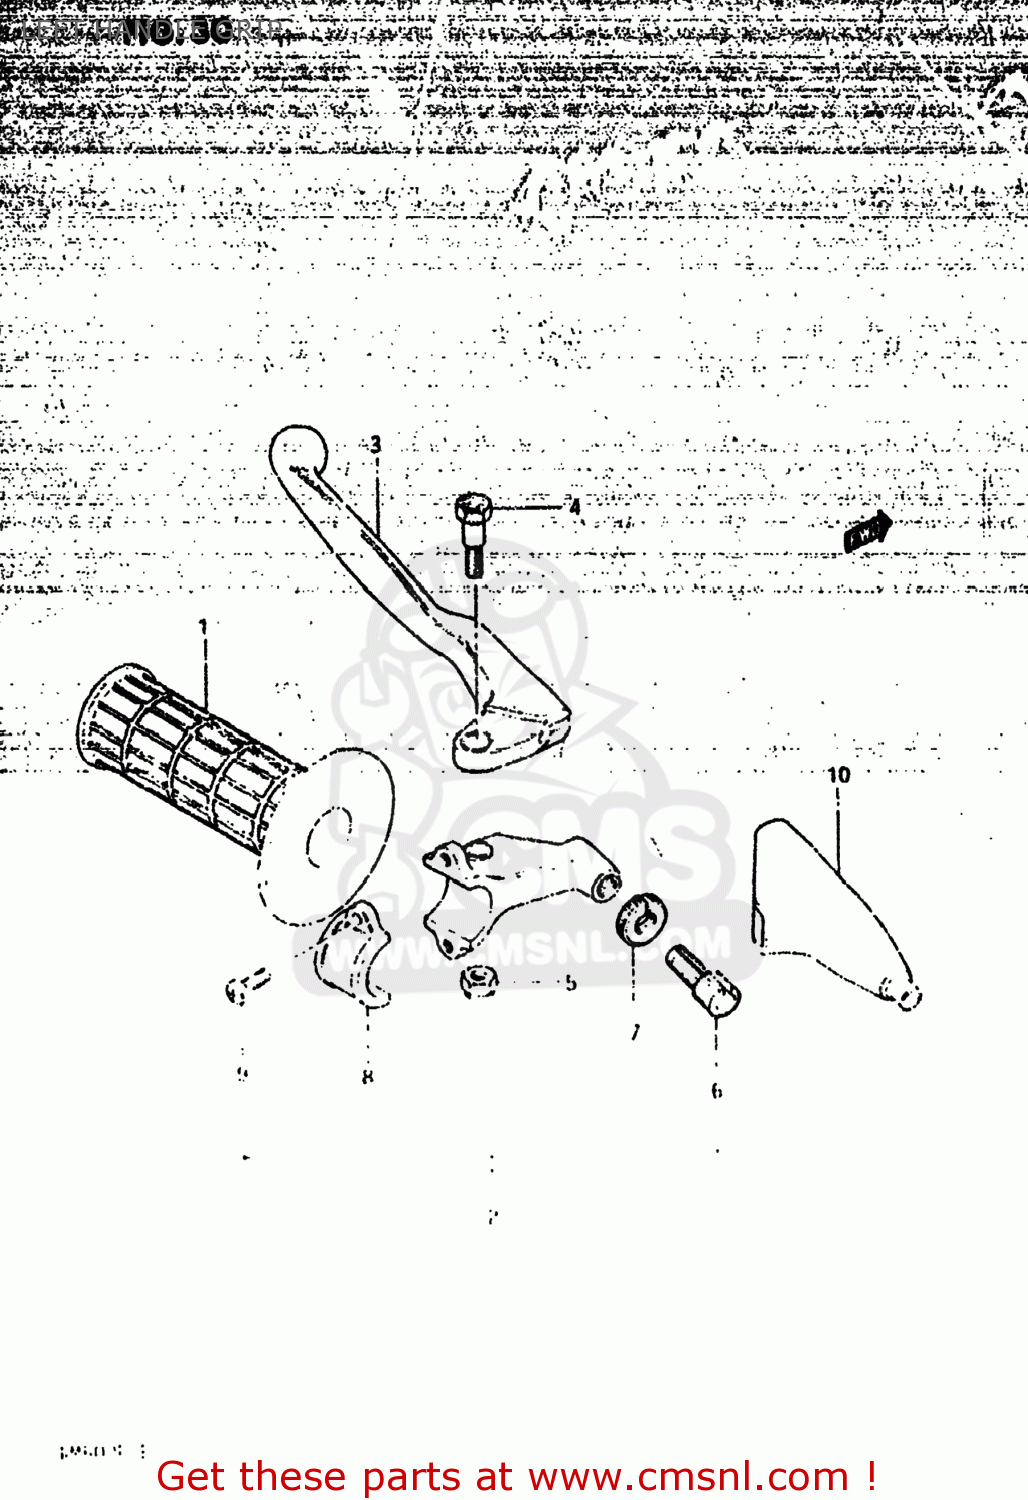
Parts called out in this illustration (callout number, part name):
1	GRIP,LEFT
2	LEVER ASSY,CLUTCH
3	LEVER,CLUTCH
4	BOLT,LEVER
5	NUT 6MM
6	ADJUSTER,CABLE
7	NUT,CABLE ADJUSTER
8	BRACKET,CLUTCH LEVER HOLDER
9	SCREW
10	COVER,CLUTCH LEVER
